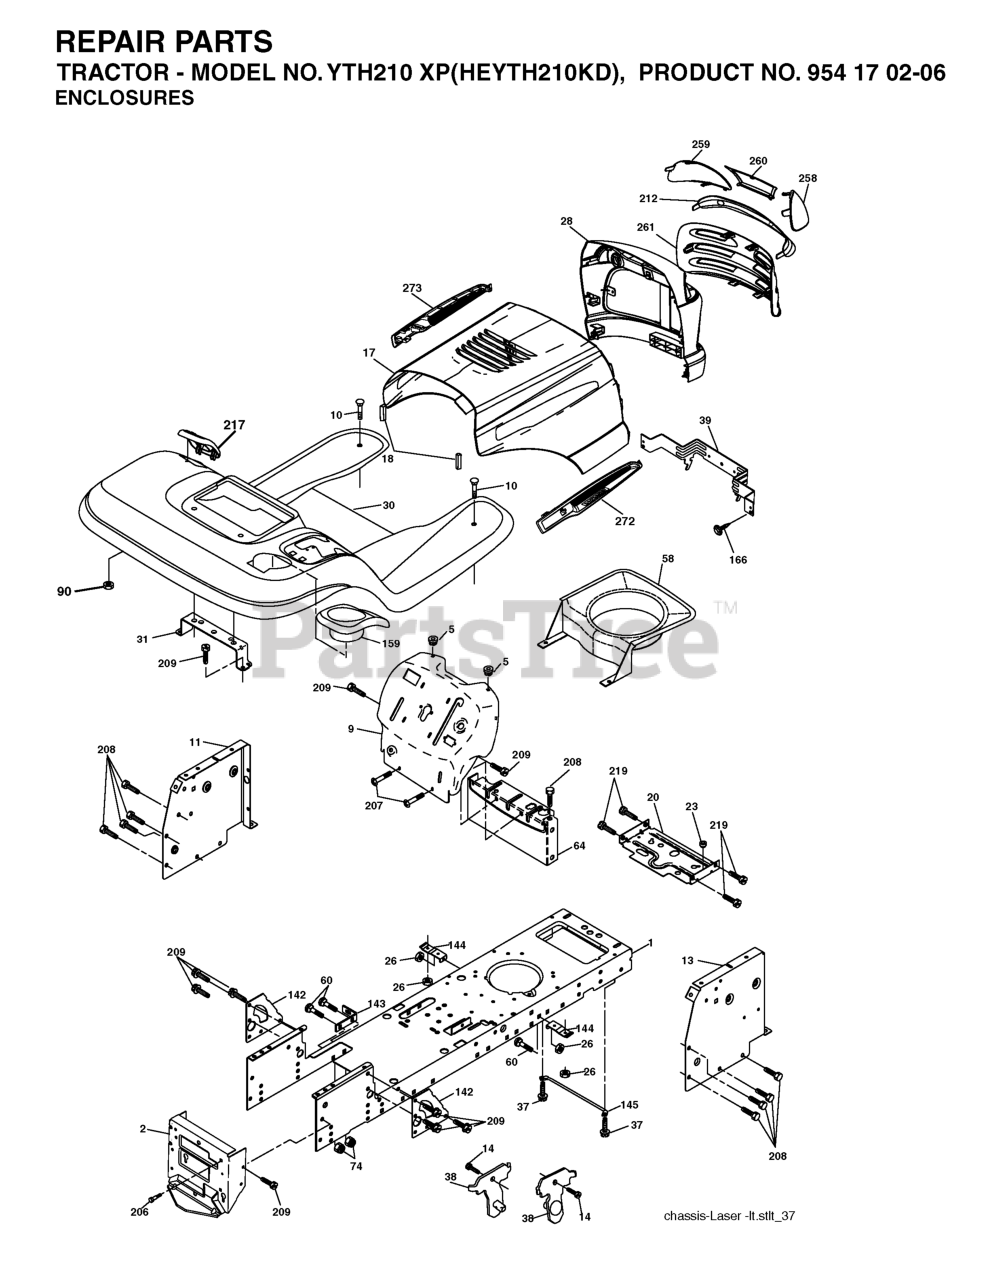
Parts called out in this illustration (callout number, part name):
1	CHASSIS STAMPING
2	DRAWBAR, 12GA
5	BUMPER.RUBBER.HOOD
10	BOLT D
11	PANEL.DASH.LH.LTX
13	PANEL ASM, DASH RH
17	VENT.HOOD.LASER.III
18	BUMPER.HOOD.LARGE.1.75"
20	PLATE MTG.BATTERY/FUEL TANK
23	BUSHING.SNAP.NYL.BLK.
26	NUT
30	FENDER STL W/CUPHOLDER
31	BRACKET.SUPPORT.FENDER
37	Screw 5/16-18 x 1/2 Hex, Self Tapping 5/16-18 x 1/2
38	BRACKET.ASM.PIVOT.MOWER.REAR
39	BRACKET PIVOT LASER
60	Bolt - Rd. Hd. Sq. Neckiage 3/8 16 x 3/4
64	DASH LOWER
90	NUT.PUSH.3/16
142	PLATE REINFORCEMENT
143	BRACKET, SWAYBAR CHASSIS
144	BRKT, FOOT REST
145	ROD PIVOT CHASSIS/HOOD
159	GREY CUP HOLDER
206	SHOULDER BOLT 5/16-18TT
207	SCREW, 5/16-18 X 1/2
208	SCREW 3/8-16X1/2
209	SCREW, 3/8-16X3/4
212	INSERT.LENS.REFLECTIVE
217	CONSOLE FUEL WINDOW
219	SCREW
258	LENS LH
259	LENS LH
260	COVER.LENS.HUSQ.LASER
272	VENT.HOOD.LASER.
273	VENT.HOOD.LASER.
278	SCREW
